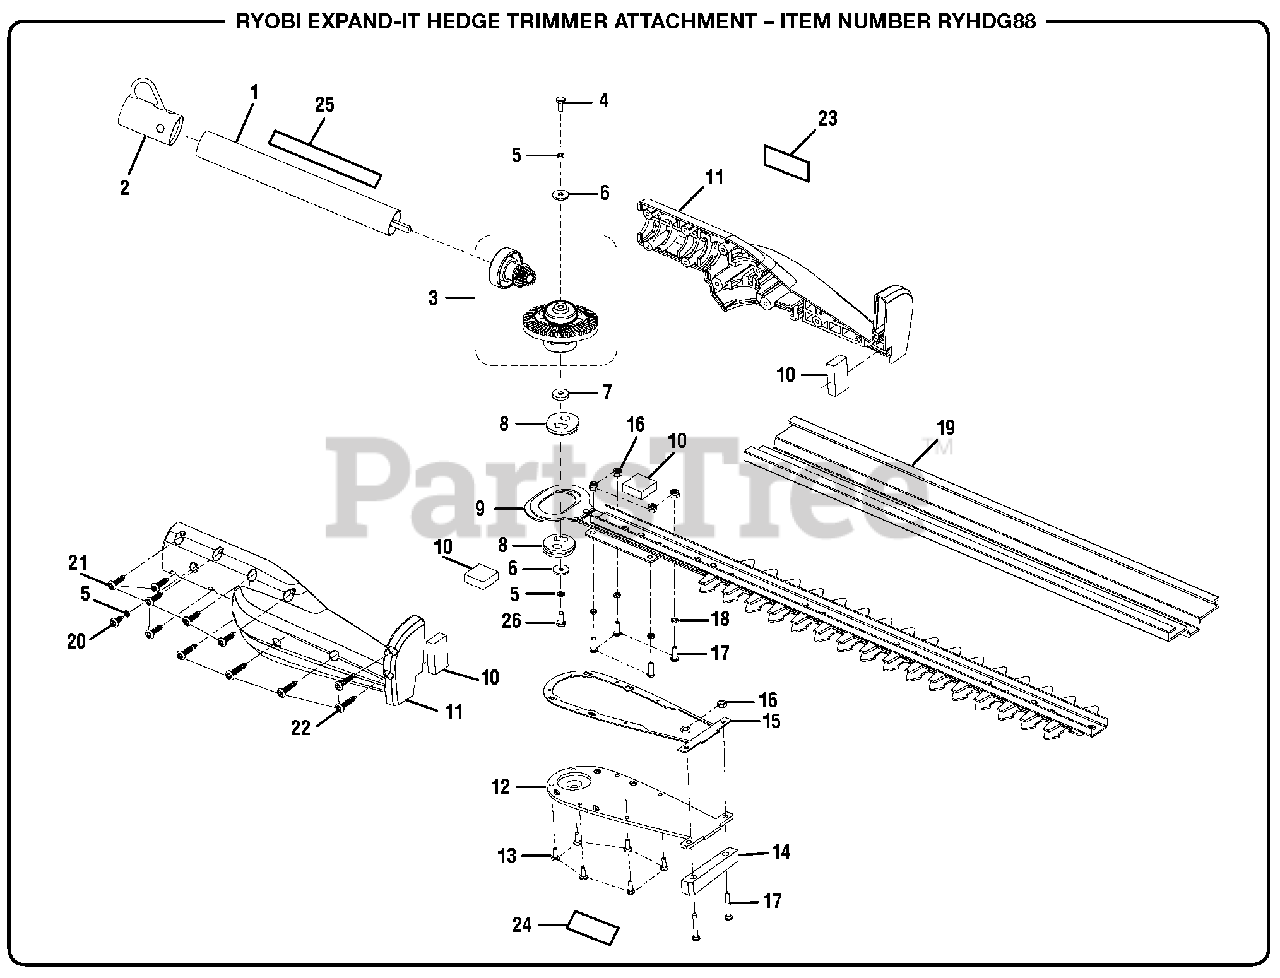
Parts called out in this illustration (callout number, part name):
1	Lower Drive Shaft Assembly
2	Hanger Cap
3	Output Gear and Pinion Assembly
4	Screw (M5 x 10 mm)
5	Spring Washer (M5)
6	Washer (M5)
7	Cam Spacer
9	Blade Assembly
10	Felt
11	Housing Assembly
12	Bottom Housing Plate
13	Screw (M4 x 16 mm)
15	Seal
16	Lock Nut (M4)
17	Screw (M4 x 16 mm)
18	Spring Washer (M4)
20	Screw (M4 x 9 mm)
21	Screw (M5 x 14.5 mm)
22	Screw (M5 x 26.5 mm)
23	Logo Label
24	Hot Surface Label
25	Warning Label
26	Screw (M5 x 12 mm, Hex Hd.)
